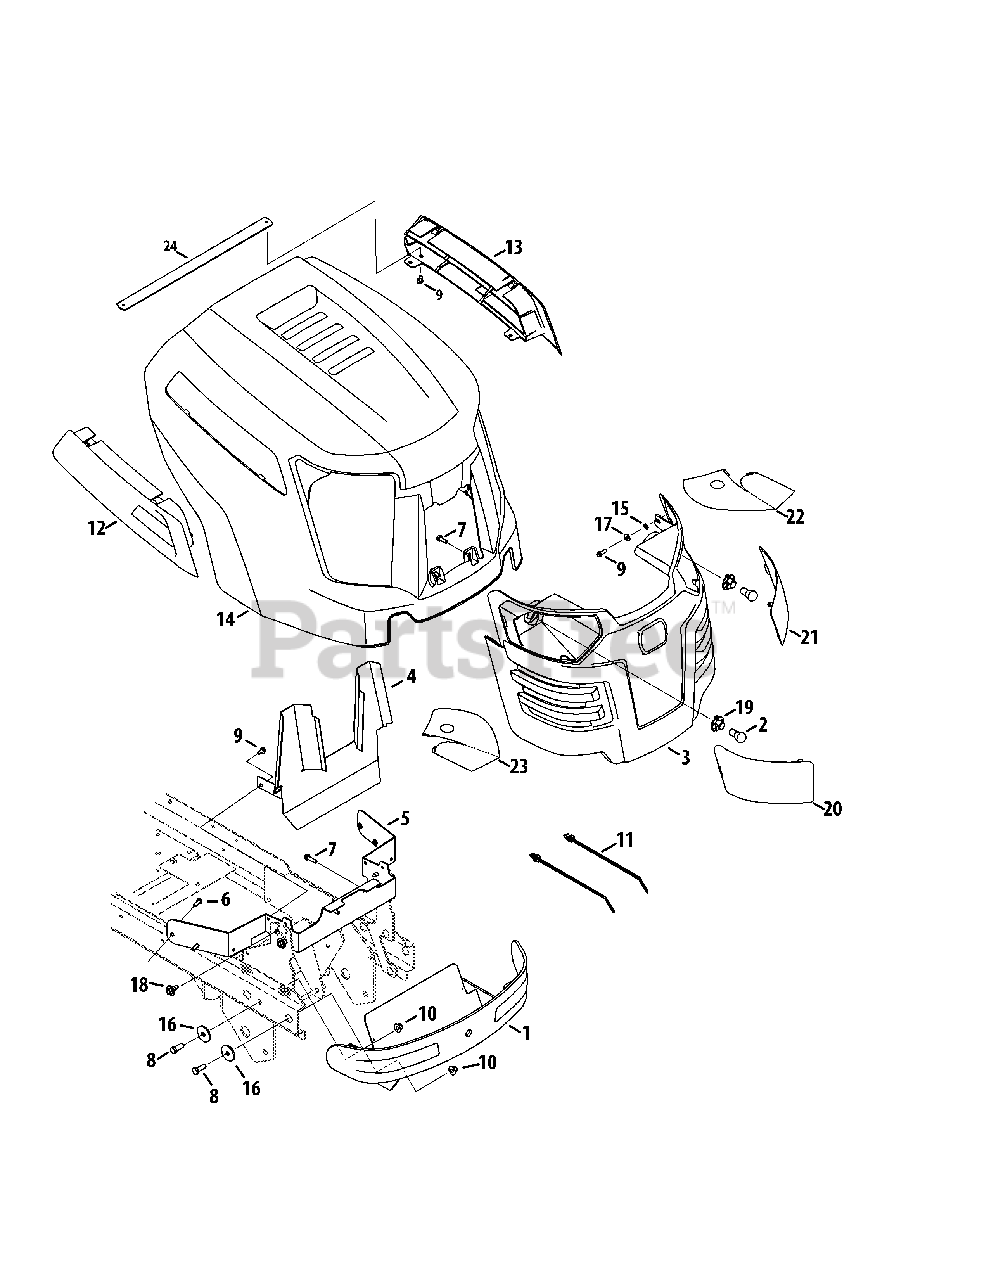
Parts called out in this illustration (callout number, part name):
1	Front Bumper Assembly
4	Heat Shield
5	Hood Pivot Bracket
6	Hex Washer Screw, 1/4 x .750
7	Hex Washer Screw, 5/16-14 x 1.00
8	Hex Screw, 3/8-16 x 1.00
9	Hex Washer Screw, 1/4-20 x 0.500
10	Flange Lock Nut, 3/8-16
11	Cable Tie, 7.5
12	RH Hood Scoop
13	LH Hood Scoop
14	Hood
15	Lock Washer, 1/4
16	Flat Washer, .390 x 1.500 x .134
17	Flat Washer, .271 x .630 x .065
18	Shoulder Screw, 5/16-18 x .43 x .29
19	1/4-turn Socket
20	RH Hood Lens
21	LH Hood Lens
22	Left Lens Reflector Label
23	Right Lens Reflector Label
